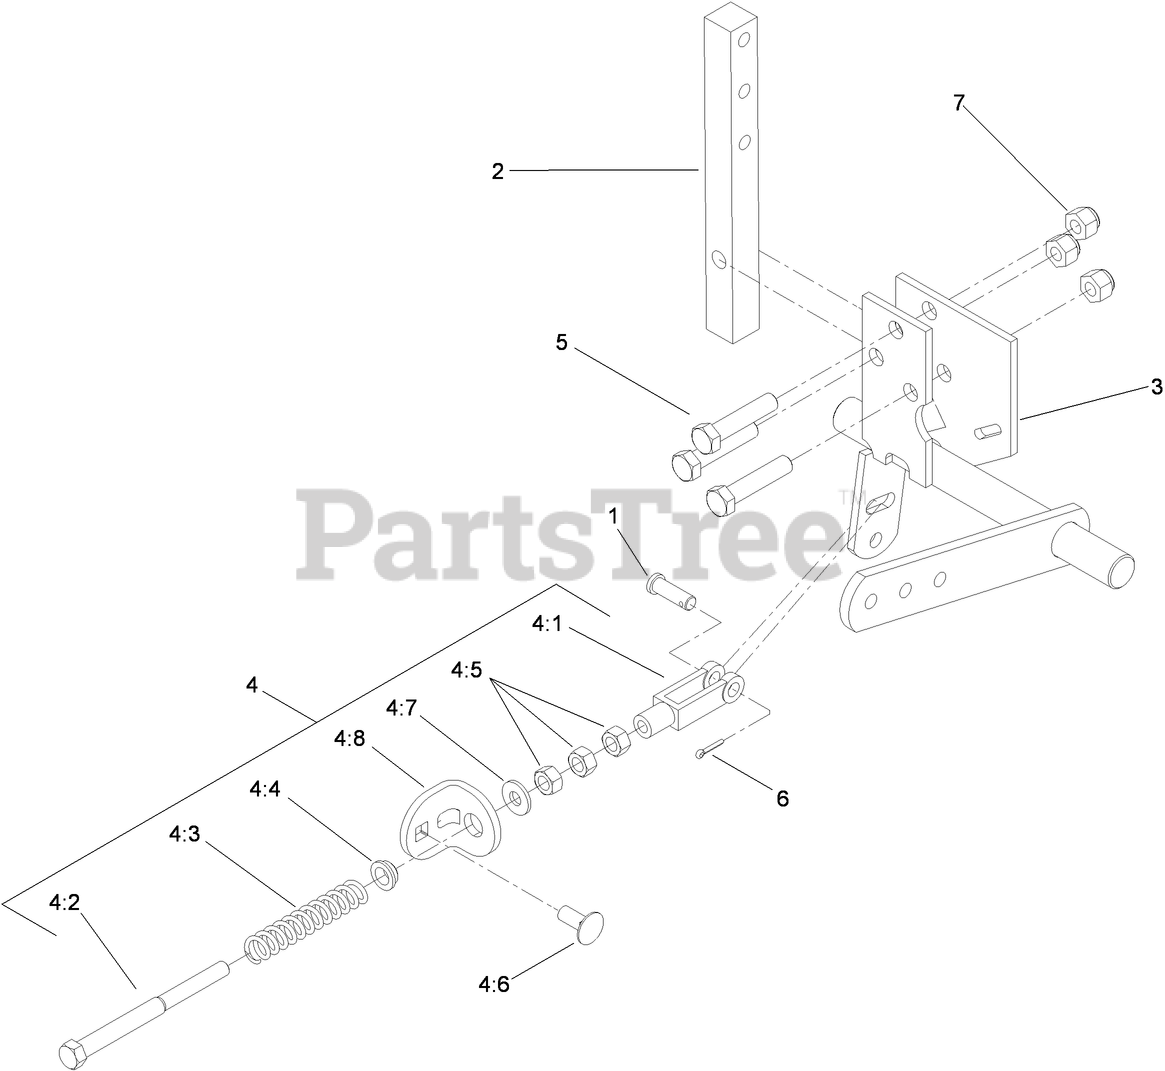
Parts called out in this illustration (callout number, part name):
1	PIN-CLEVIS
2	ARM-SHAFT, CONTROL
3	CONTROL-MOTION, LH
4	NEUTRAL RETURN ASM
4:1	YOKE-ADJUSTABLE
4:2	BOLT-RETURN, NEUTRAL
4:3	SPRING-RETURN, NEUTRAL
4:4	BUSHING-NYLON, FLANGED
4:5	NUT-HEX
4:6	SCREW-CARR
4:7	WASHER-FLAT
4:8	TAB-ADJUSTMENT
5	SCREW-HH
6	PIN-COTTER
7	NUT-LOCK, NI
